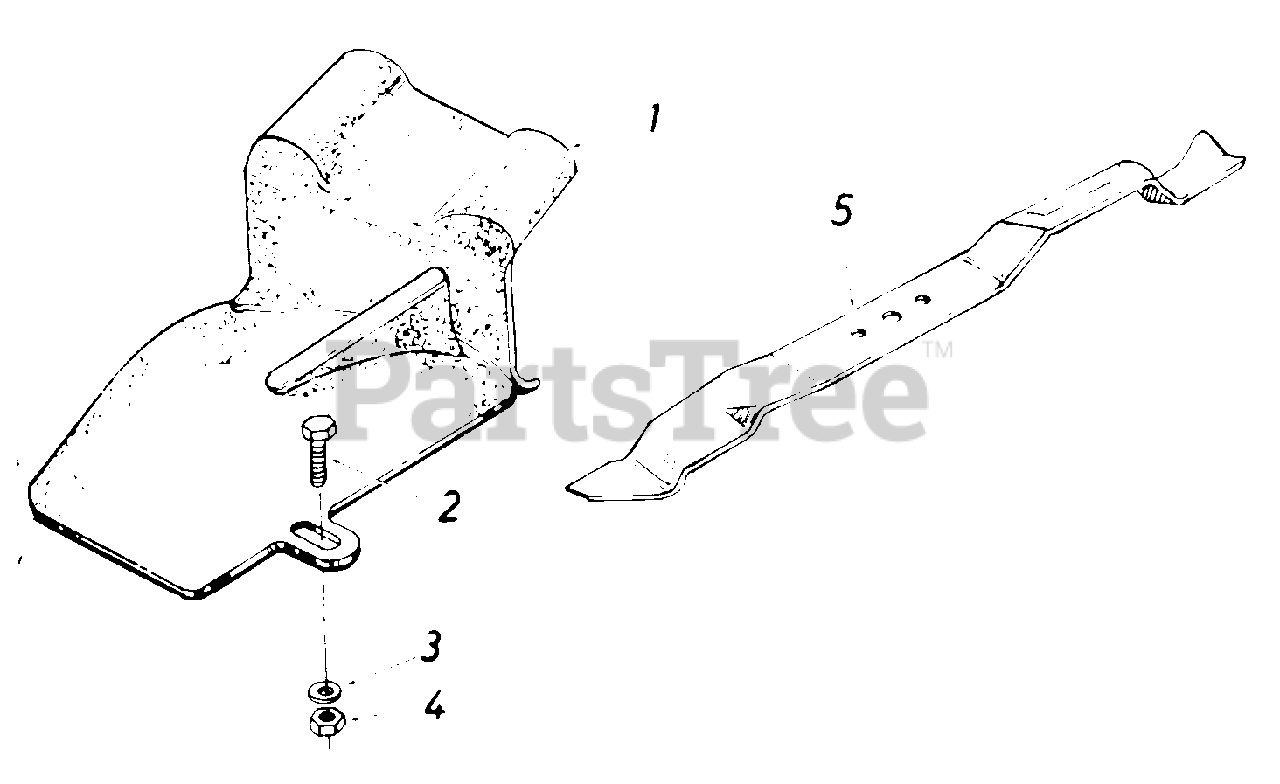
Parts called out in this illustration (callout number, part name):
1	Mulching Baffle
2	Hex Bolt 1/4-20 x .88" Lg.*
3	Belleville Wash. .265 I.D. x. .75 O.D. x .093
4	Hex Jam Nut 1/4-20 Thd.
5	20" Mulching Blade
